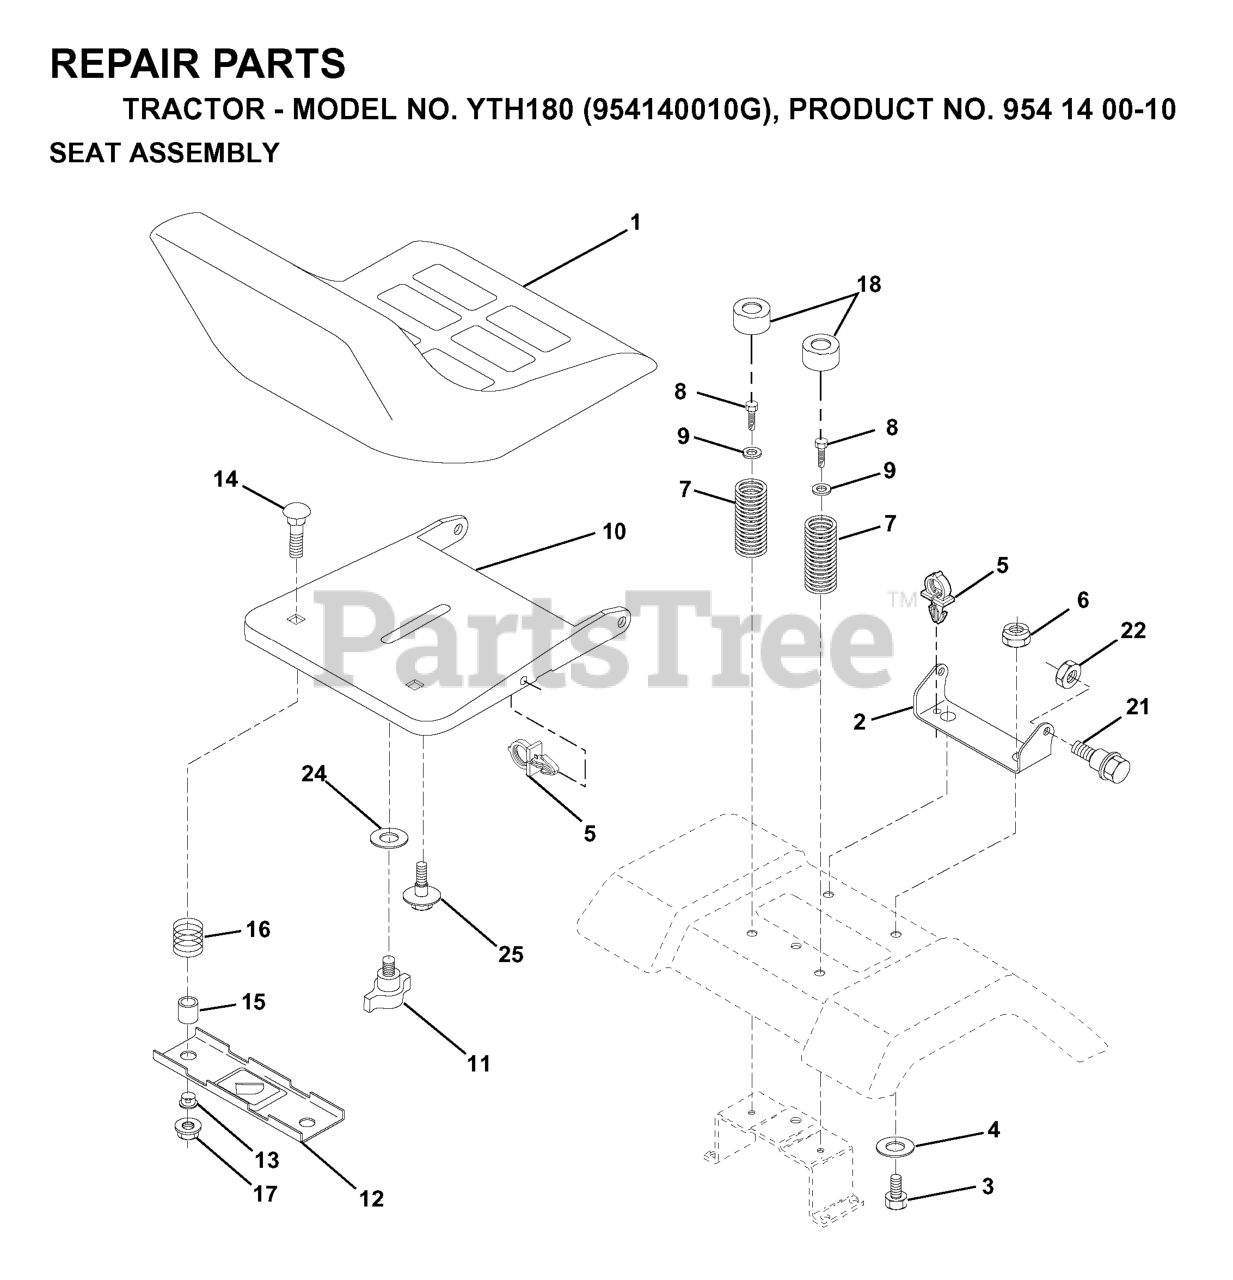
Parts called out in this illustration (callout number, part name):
1	SEAT, GRAY
2	SEAT PIVOT BRKT
3	BOLT
6	NUT
7	SPRING COMPRESSION
8	SCREW GTV
9	WASHER
10	PAN, SEAT
11	KNOB 1/2" YT
12	BRKT SWITCH
14	BOLT.ROUND.HEAD.SQUARE.NECK
15	SPACER SPLIT
16	SPRING COMPRESSED
17	NUT T
18	CAP SPRING
21	BOLT SHOULDER 5/16-18
22	NUT.71038.31-18.HEX.NYLOCK
25	BOLT,SHOULD
